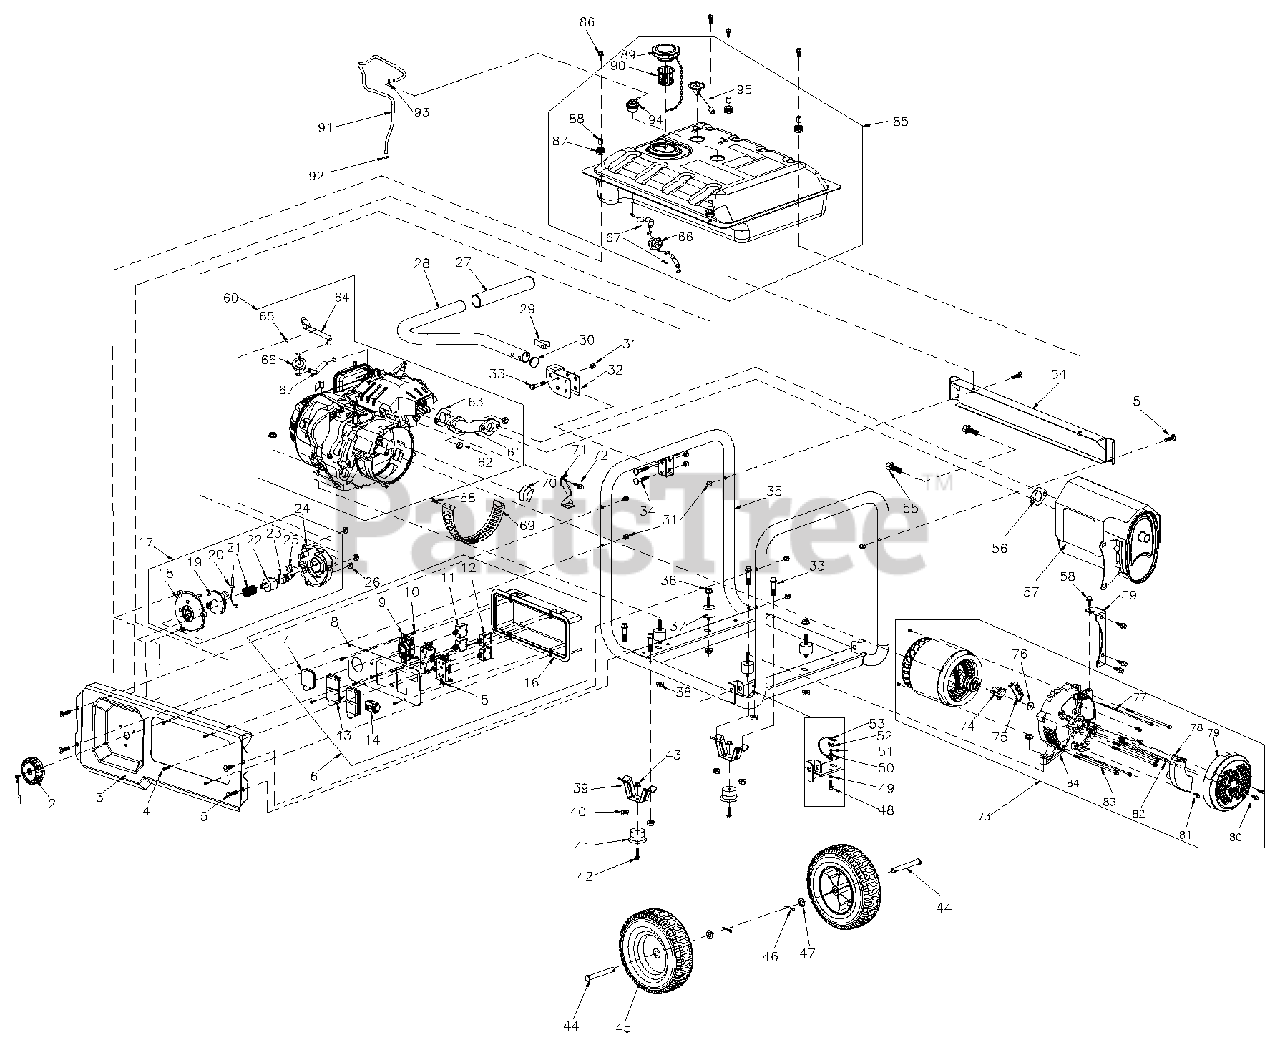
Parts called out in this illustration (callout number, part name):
1	SCREW, PLATE M5X10
2	KNOB, POWER DIAL
3	RAIL, FRAME, CP SIDE
4	SCREW, SELF TAPPING, ST4.0X16
5	BOLT, CURVED HEAD, M8X40
6	PANEL ASSY., CONTROL
7	COVER, OUTLET
8	FACE PLATE, CONTROL PANEL
9	OUTLET, 30A 120/250V SPCGR
11	BREAKER, CIRCUIT 25A
12	BREAKER, CIRCUIT 20A
13	COVER, OUTLET
14	METER, HOUR
15	OUTLET, 20A 120V DUPLEX 6342
16	COVER, CONTROL PANEL BACK
17	SWITCH, COMB , POWER DIAL ASSY.
18	COVER, POWER DIAL
19	SHAFT, POWER DIAL
20	CHOKE, LASSO
21	SPRING, POWER DIAL
22	ADAPTER, POWER DIAL
23	SWITCH, FUEL, POWER DIAL
24	CASE, POWER DIAL
25	SWITCH, MICRO
27	GRIP, HANDLE
28	HANDLE, BLACK
29	BUTTON, SNAP
30	PLUG, HANDLE
31	CAP, LOCKING NUT
32	BRACKET, BLACK
33	BOLT, M8X45
34	BOLT, CARRIAGE HEAD
35	FRAME, BLACK
36	NUT M10
37	MOUNT, RUBBER VIBRATION
39	FRAME, BENT FOOT
40	NUT, M8
41	FOOT, RUBBER
42	BOLT, M6X28
43	NUT, M6
44	PIN, AXLE
46	PIN, COTTER
47	WASHER, FLAT, 13X2
48	BOLT, M6X20
49	WASHER, SPECIAL LOCK
51	WASHER, FLAT, 6X0.8
52	NUT, M6
53	WIRE ASSY., GROUND
54	RAIL, BACK
55	BOLT, M8X25
56	GASKET, MUFFLER EXHAUST
57	MUFFLER
58	BOLT, M8X16
59	BRACKET, MUFFLER
60	ENGINE, 389CC
61	PIPE, EXH. MANIFOLD
63	GASKET, EXHAUST CYLINDER
64	HOSE, FUEL 12.7X250
65	CLAMP, 012
66	FILTER, FUEL
67	HOSE, FUEL 12.7X75
68	BOLT, M5X10
69	COVER, DUST
71	BRACKET, AIR CLEANER
72	BOLT, M6X12
73	ALTERNATOR ASSY.
74	BRUSH, ALTERNATOR
75	TERMINAL, WIRE CONNECTION
76	WASHER, FLA M10X4
77	BOLT, M5X204
79	COVER, GENERATOR END
80	BOLT, M5X12
81	BOLT, M5X16
82	BOLT, ROTOR, M10X255
83	BOLT, M6X165
84	HOUSING, BEARING, RR
85	TANK ASSY, FUEL 7 GAL
86	BOLT, M8X20
87	MOUNT, RUBBER, FUEL TANK
88	LINING INSERT, ANTI-CRUSH
89	CAP, FUEL
90	FILTER, FUEL
91	HOSE, FORMED ROV TO AIR BOX
92	CLAMP, 012
93	CLAMP, 010
94	ROV
95	GAUGE, FUEL
